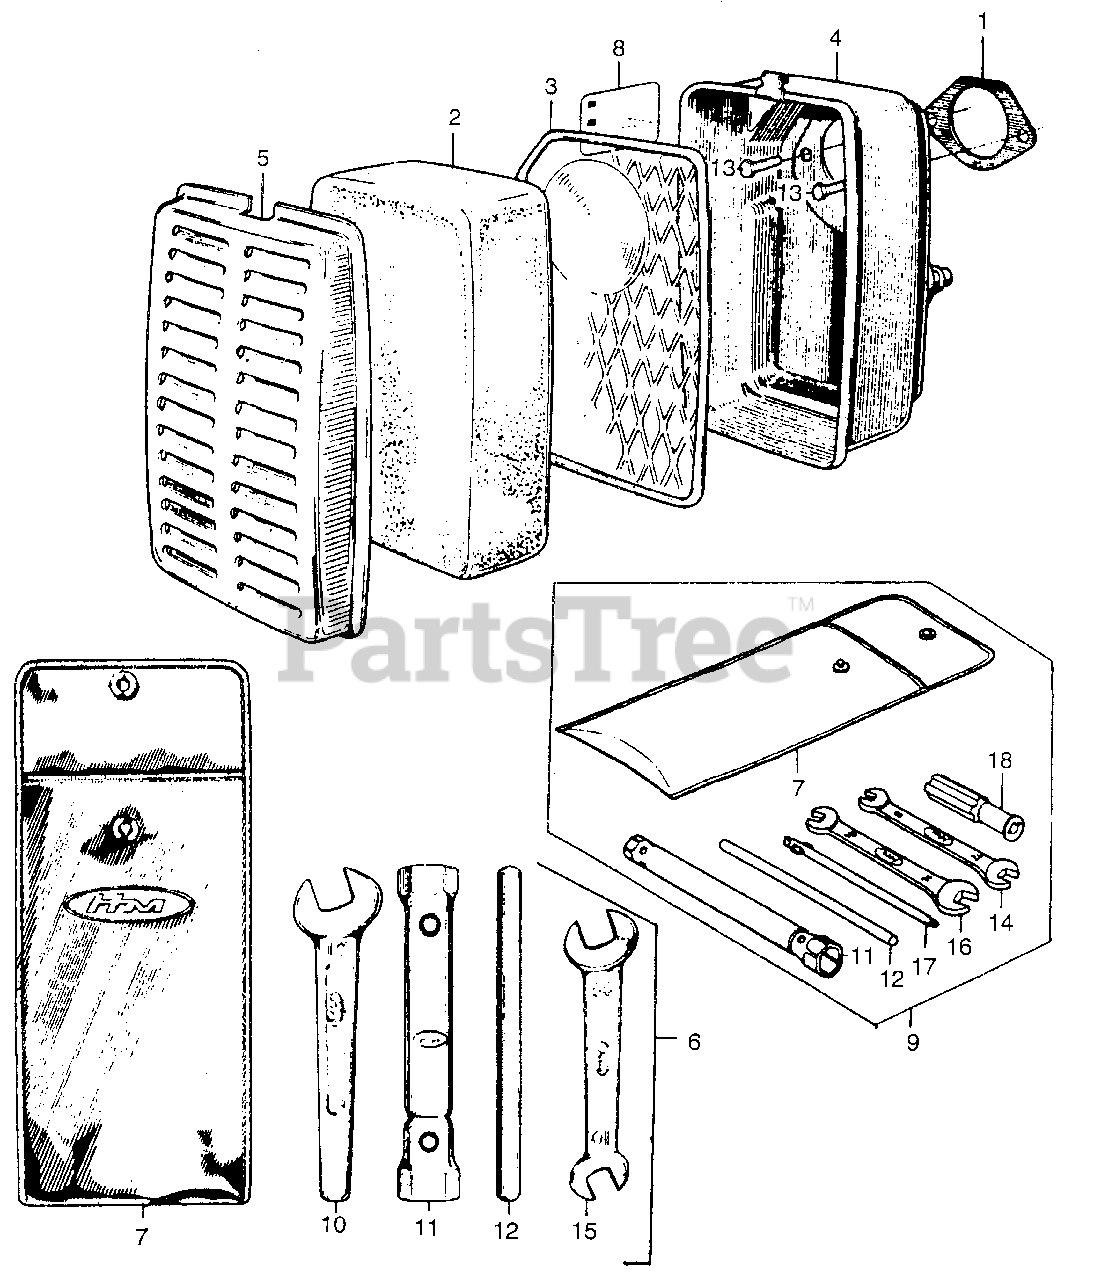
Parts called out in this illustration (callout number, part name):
1	GASKET, AIR CLEANER (NOT AVAILABLE)
2	ELEMENT, AIR CLEANER
3	GRID, AIR CLEANER (NOT AVAILABLE)
4	HOUSING, AIR CLEANER *R2L* (SCARLET) (NOT AVAILABLE)
5	COVER, AIR CLEANER *R2* (SCARLET) (NOT AVAILABLE)
6	TOOL SET (NOT AVAILABLE)
8	LABEL, AIR CLEANER CAUTION (NOT AVAILABLE)
10	WRENCH, OPEN END (7MM)
11	WRENCH, SPARK PLUG (NOT AVAILABLE)
12	HANDLE, BOX WRENCH
13	BOLT, HEX. (6X12)
15	SPANNER (10X14)
